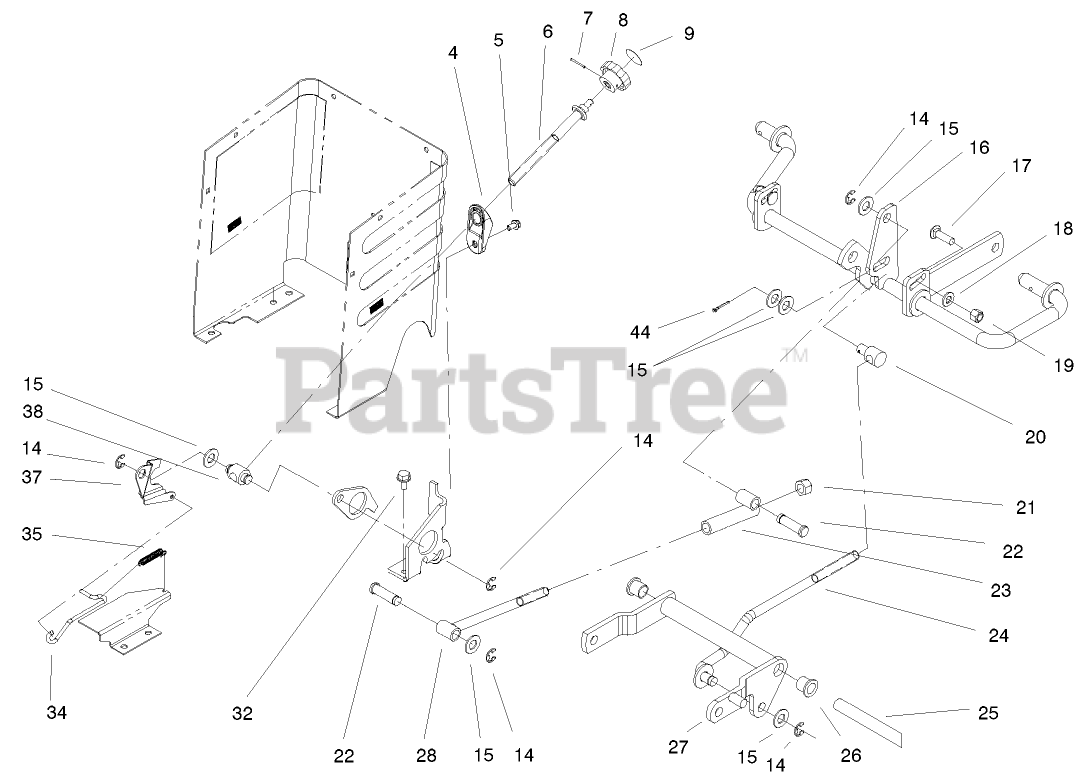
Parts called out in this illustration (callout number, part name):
4	WEDGE - HOC
5	SCREW-HWH
7	PIN-SPIROL
14	RING-RETAINING, EXTERNAL
15	WASHER-FLAT
16	SHAFT-GAGE
17	BOLT-CARR
18	WASHER-FLAT
19	NUT-LOCK, NI
21	NUT-LOCK, NI
26	BUSHING-FLANGE
27	ARM-PIVOT
32	SCREW-HWHTF
34	ROD - HOC INDICATOR
35	SPRING - EXTENSION
37	PLATE - HOC GAGE
44	PIN-COTTER
